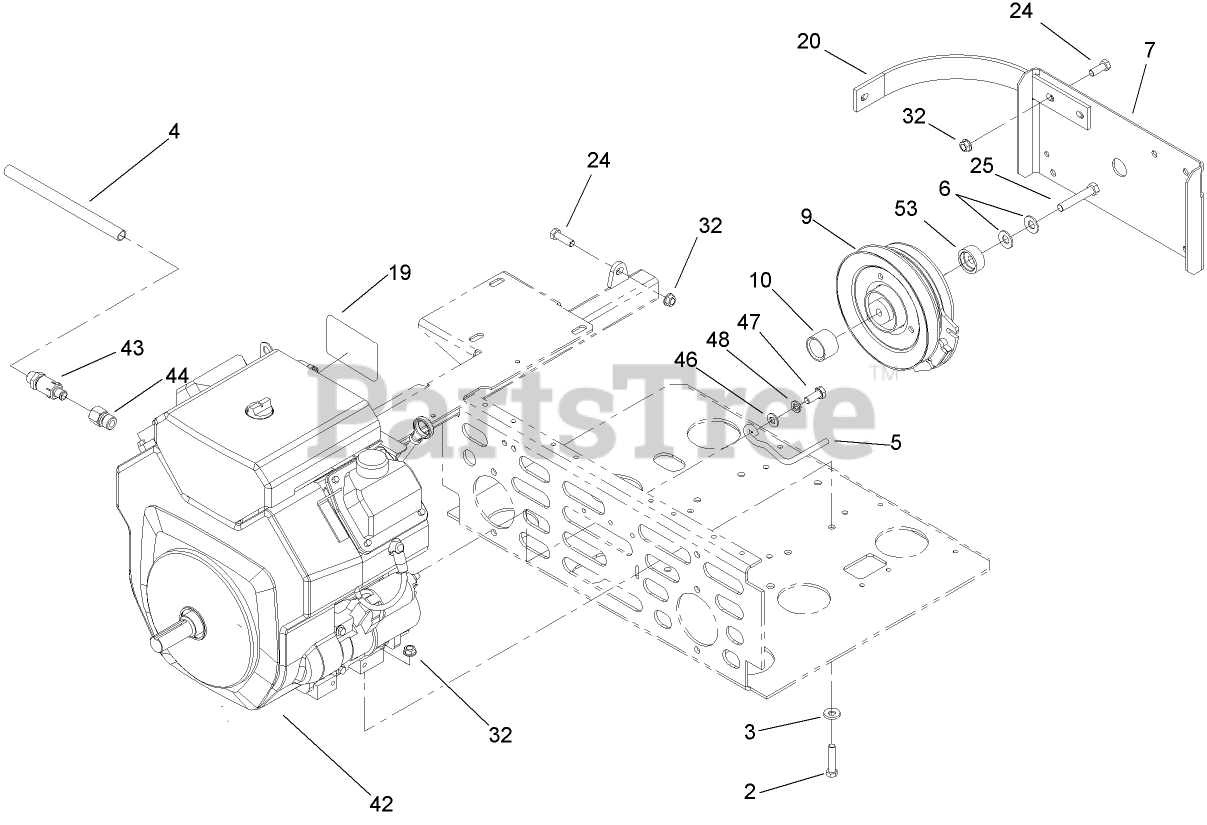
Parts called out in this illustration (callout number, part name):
2	SCREW-HH
3	WASHER-BELLEVILLE
4	TUBE-DRAIN, OIL
5	ROD-BELT
6	WASHER-SPRING
7	GUARD-CLUTCH
9	CLUTCH-ELECTROMAGNETIC
10	SPACER-CLUTCH
20	STRAP-GUARD
24	SCREW-HH
25	SCREW-HH
32	NUT-HHF, WHIZ
43	VALVE-DRAIN, OIL
44	Adapter
46	WASHER-FLAT
47	SCREW-HH
48	WASHER-BELLEVILLE
53	KEEPER-CLUTCH
